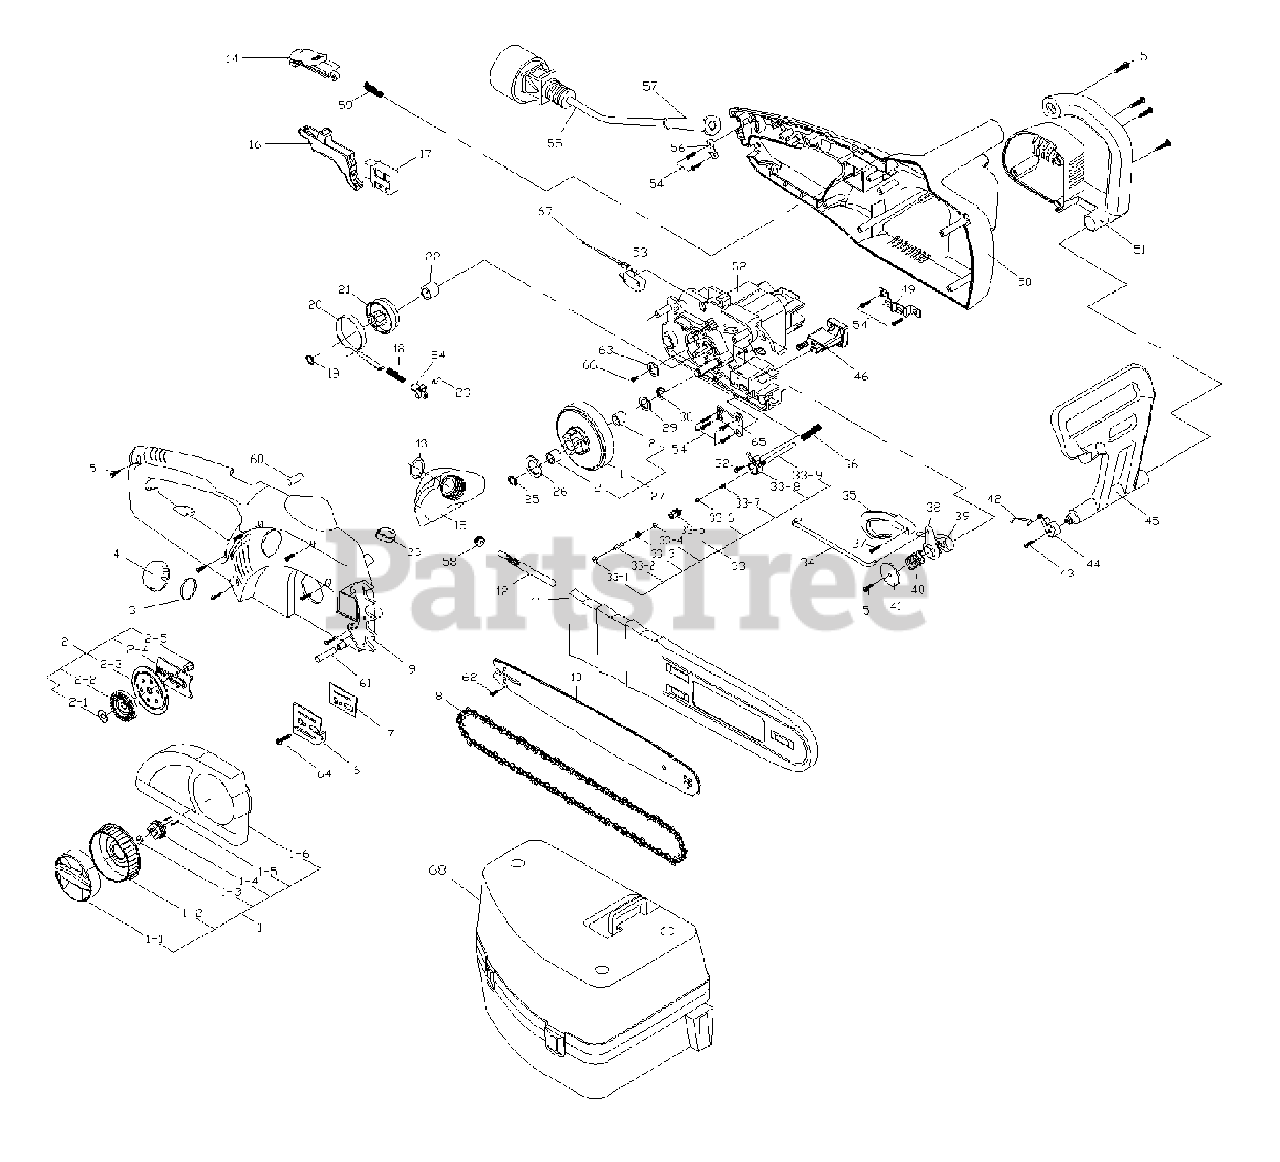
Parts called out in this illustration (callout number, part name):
2	CHAIN COVER ASS'Y
4	OIL COVER
6	ADJUSTMENT PLATE
11	COVER
12	OIL PIPE ASS'Y
14	SWITCH BUTTON
20	SPRING, BRAKE
22	ADJUSTMENT COVER
27	GEAR BEARING ASS'Y
30	C RING
33	OIL PUMP ASS'Y
42	CONNECTING BAR
44	CONNECTOR
45	FRONT-HAND GUARD
50	HOUSING (L)
51	REAL COVER
52	MOTOR GEAR BOX ASS'Y
55	POWERCORD
56	STRAIN RELIEF
57	CORD GUARD
68	CARRY CASE
